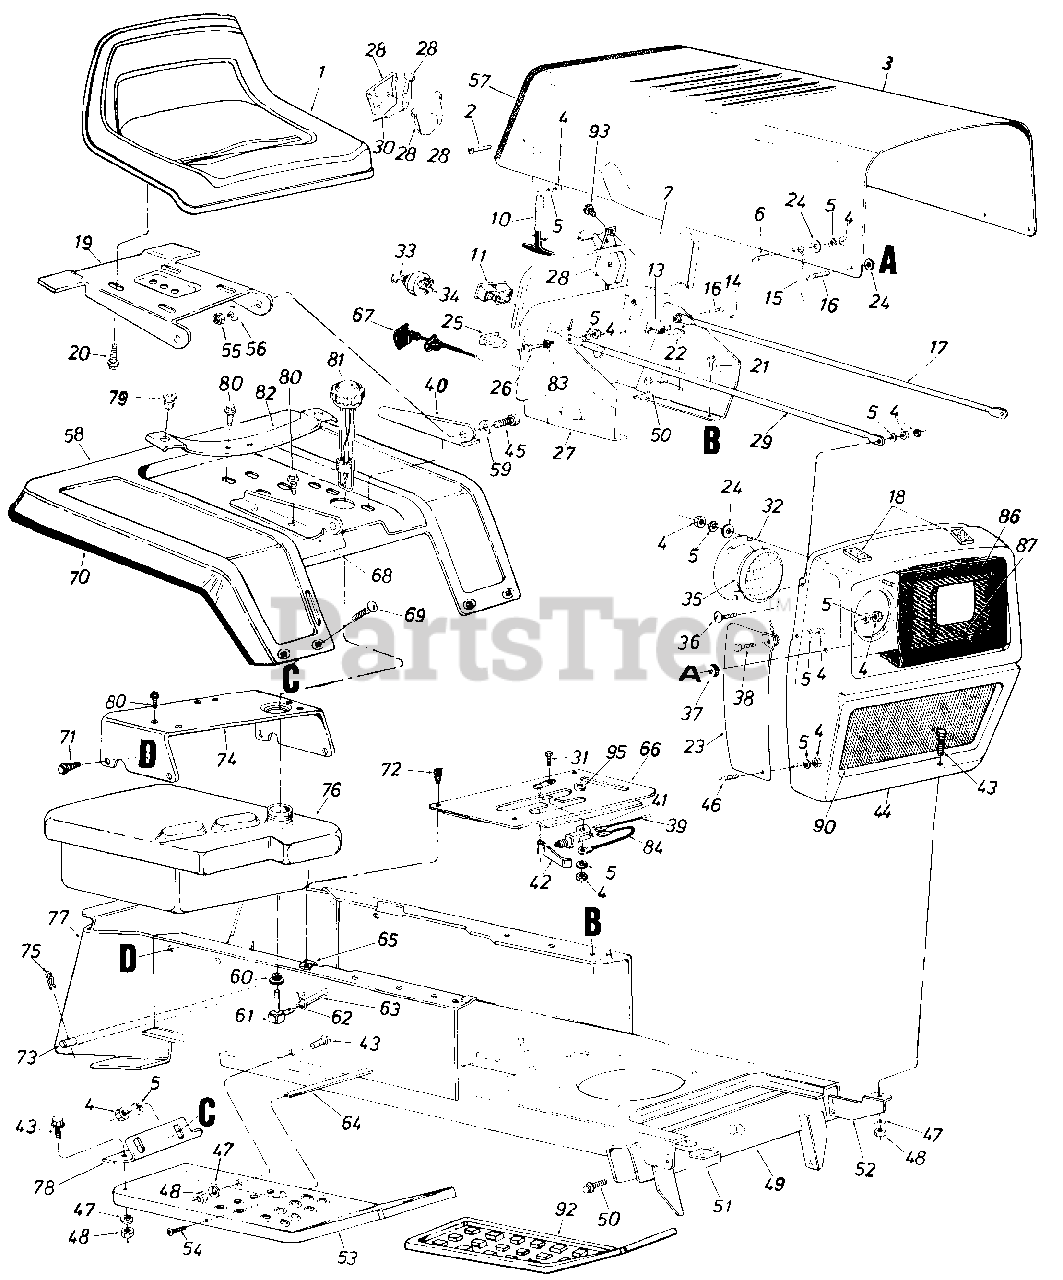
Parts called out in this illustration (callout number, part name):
1	Seat Assembly
2	Truss Mach. Scr. 1/4-20 x .50" Lg.
5	L-Wash. 1/4" Scr.
6	Truss Mach. Scr. 1/4-20 x .50" Lg.
7	Vinyl Molding Strip-29"
10	Hood Latch Ass'y.
11	Ammeter
13	Circuit Breaker 8 Amp.
14	Hex Tap Scr. #10 x .50" Lg.
15	Hood Stop
16	Truss Mach. Scr. 1/4-20 x .75" Lg.
17	Grille Positioning Rod
18	PVC Foam Strip 1/2 x 1.00" x 2.00" Lg.
19	Seat Pivot Brkt.
20	Hex Wash. Hd. AB-Tap Scr. 3/8 x .75" Lg.
21	Hex Thd. Rolling Scr. 1/4" x .50" Lg.
22	Speed Nut #10Z
23	Grille Side Panel-R.H.
24	Fl-Wash. 1/4" I.D.
25	Light Switch
26	Truss Hd. Scr. 1/4-20 x 1.00" Lg.*
27	Dash Panel Ass'y.
28	Throttle Control Box Comp.
29	Grille Positioning Rod
30	Throttle Control Cable
31	Hex Bolt 1/4-20 x .50" Lg.
32	Head Lamp Retainer
33	Ignition Key
34	Ignition Switch
35	Head Lamp
36	Truss Machine Scr. 1/4-20 x .75" Lg.
37	Rubber Wash. .50" I.D. x 1.00 O.D. x .25 Thk.
38	Truss Mach. Scr. 1/4-20 x .50" Lg.
39	Reverse Lockout Wire Harness
40	Seat Bracket-L.H.
41	Safety Switch
42	Switch Actuator Spring Lever
43	Hex Scr. 5/16-18 x .75" Lg.
44	Grille Ass'y.
45	Hex Bolt 5/16-18 x .75" Lg.
46	Truss Mach. Scr. 1/4-20 x .50" Lg.
47	L-Wash. 5/16" I.D.
48	Hex Nut 5/16-18 Thd.
49	Lower Frame Ass'y.
50	Hex Thd. Rolling Scr. 5/16" x.75" Lg.
51	Grille Mount Brkt.-R.H.
52	Grille Mount Brkt.-L.H.
53	Running Board-R.H.
54	Truss Mach. Scr. 5/16-18 x .75" Lg.
55	Hex Cent. L-Nut 5/16-18 Thd.
56	Bell-Wash. .34" I.D. x .88 O.D.
57	Vinyl Moulding Strip-30"
60	Bushing
61	90ø Nipple
62	Hose Clamp 3/8"
63	Gas Line 46" Lg.
64	Running Board Rod
65	Speed Nut #10-24
66	Transmission Cover Ass'y.
67	Choke Control Comp.
68	Seat Bracket-R.H.
69	Carr. Bolt 1/4-20 x .50" Lg.
70	Trim Strip-81" Lg.
71	Hex Thd. Rolling Scr. 5/16-24 x .75" Lg.
72	Truss Hd. Scr. #10 x .50" Lg.
73	Hitch Rod
74	Seat Mounting Channel
75	Internal Cotter Pin
76	Gas Tank
77	Hitch Plate
80	Hex Wash. Hd. Self-Tap Scr. 5/16-18 x .50" Lg.
81	Gas Gauge
82	Seat Spring
83	External Wash. 1/4" I.D.
84	Electric Wire
86	Headlight Bezel
87	Hex Wash. Hd. F-Tap Scr. #8-32 x .38" Lg .
90	Grille Screen
92	Foot Pad
93	Truss Mach. AB-Tap Scr. #10 x .50" Lg.
95	Snap Bushing
